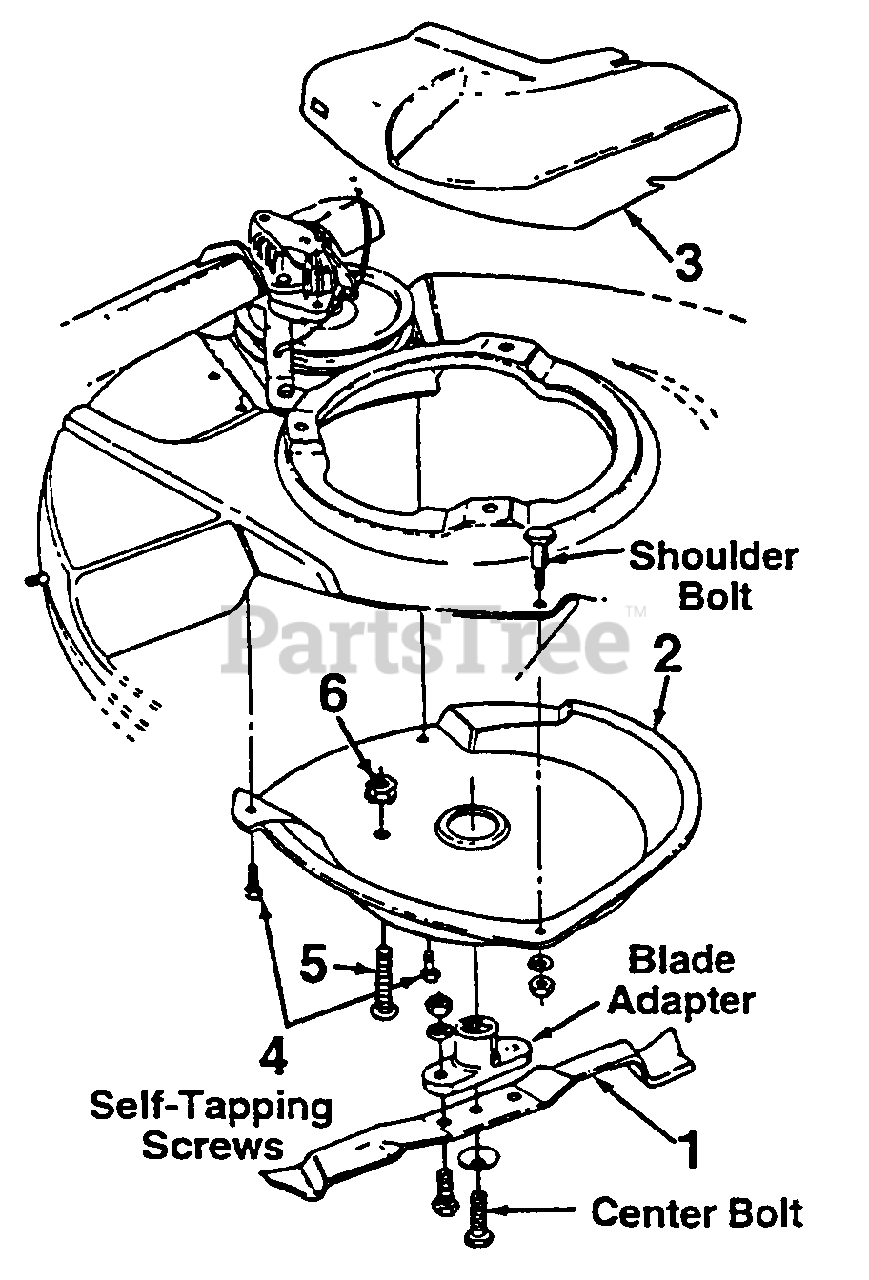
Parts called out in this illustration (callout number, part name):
1	Mulching Blade
4	Self-Tapping Screw
5	Phillips Scr. 1/4-20 x 1.5" Lg.
6	Hex Sems Nut 1/4-20 Thd.
